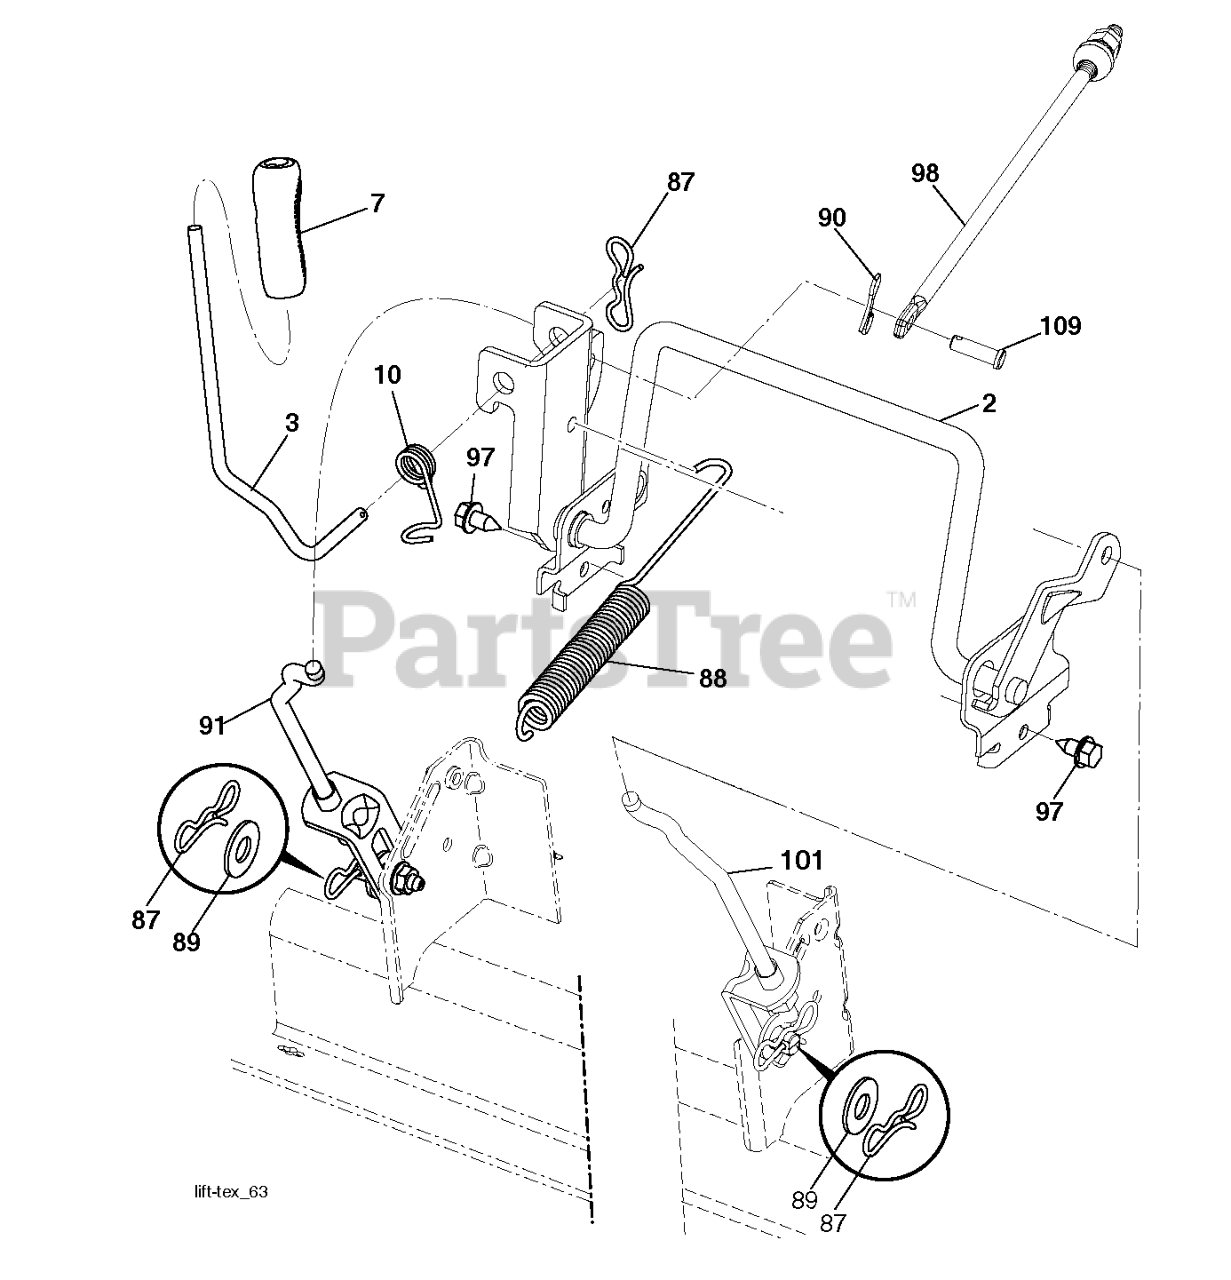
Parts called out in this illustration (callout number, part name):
2	SHAFT LIFT DECK WELD
3	Levers
7	GRIP.HANDLE.LIFT.PVC.BLACK
10	SPRING.TORSION.LIFT.HANDLE
87	PIN.COTTER.7/16.BOW TI.
88	SPRING.DK.LIFT.97/107.TXCRDII
89	WASHER.CLEAR.ZINC
90	PIN.COTTER.5/16.BOW TI
109	PINS
109	PIN CLEVIS, 3/8 X 1 1/4
